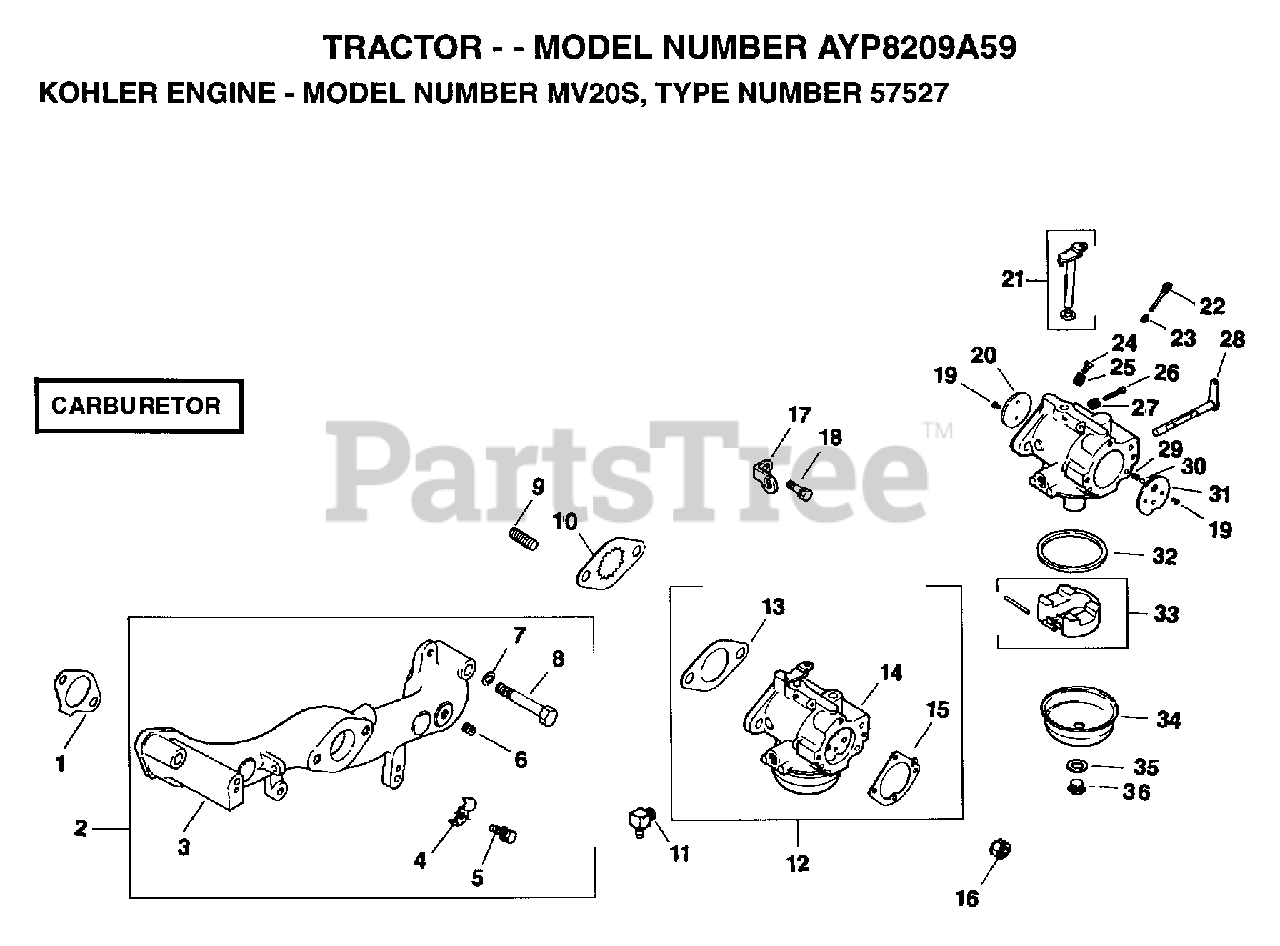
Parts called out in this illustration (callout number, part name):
4	CLAMP
5	SCREW
6	PLUG
7	WASHER
8	SCREW, 5/16-18X1-1/4 (4)
12	KIT, CARB W/GASKET
13	GASKET
14	CARBURETOR ASSY
15	GASKET, AIR CLEANER
16	NUT
17	STRAP
18	SCREW
21	SHAFT, THROTTLE
36	SCREW, BOWL RETAINER
